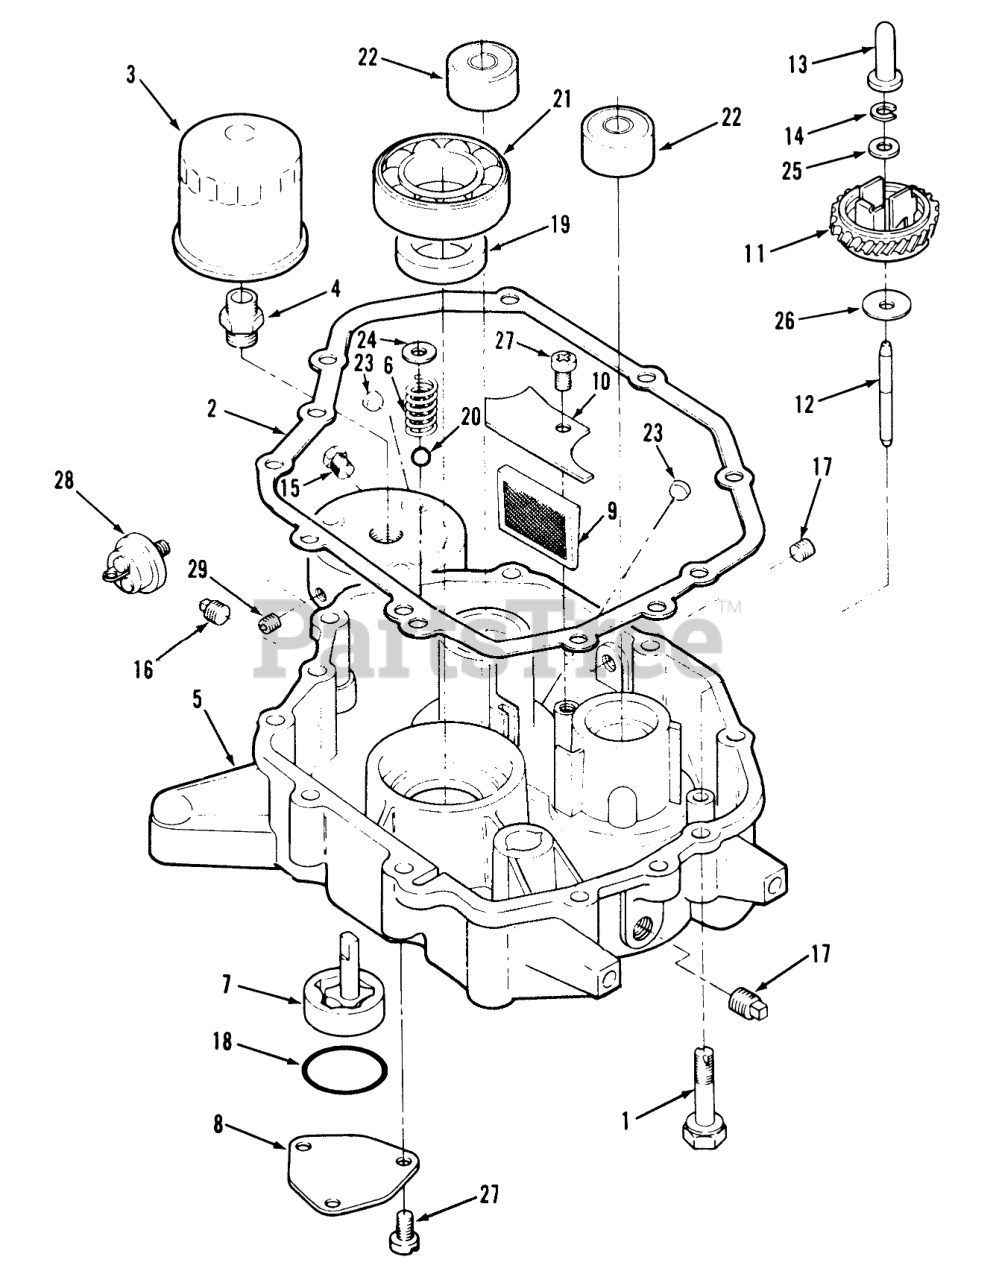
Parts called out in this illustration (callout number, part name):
1	SELF-TAP BOLT SP M8
2	Gasket
3	Oil Filter
4	Oil Filter Adapter
5	BASE-0IL
6	Spring
7	PUMP-OIL
8	COVER-OIL PUMP
9	SCREEN
10	COVER
11	Gear (Includes shafts and weights)
12	SHAFT-GOVERNOR
13	Sleeve
14	STOP-GOVERNOR
15	PLUG-HEX HD
16	Plug
18	RING-O
19	SEAL-OIL CRNKSHFT UP
20	BALL-BEARING
21	BRNG-BALL CRANKSH L
22	Ball Bearing
23	Plug
24	RETAINING-RING
25	WASHER-1.6MM THK
26	WASHER-1MM THK
27	SCREW
28	SWITCH-OIL PRESSURE
29	Plug
